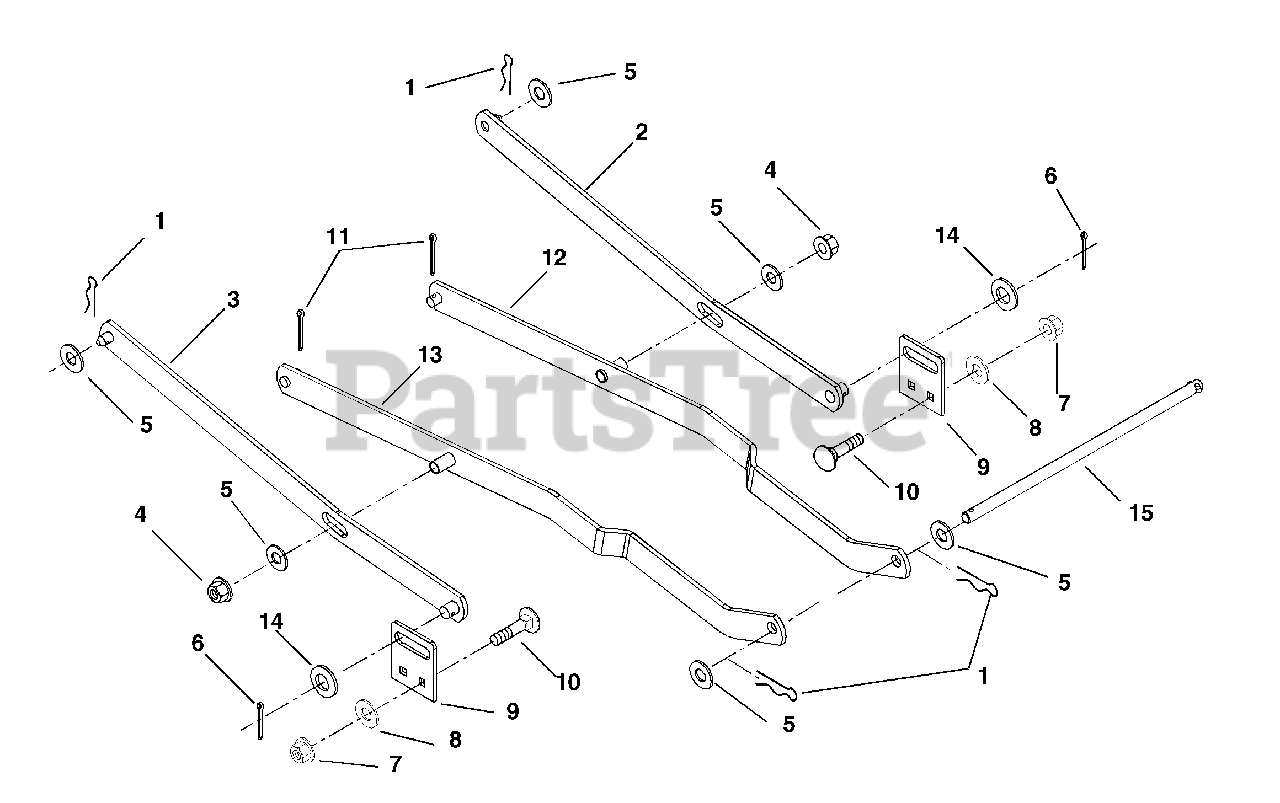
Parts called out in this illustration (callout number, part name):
1	PIN-HAIR-EXT .12X.31X2.37 YWZC
2	ARM, LIFT-LEFT REAR
3	ARM, LIFT-RIGHT REAR
4	@NUT-LK-CTR .62-11 YWZC
5	@WSHR-FL-STL.656X1.31X.095 YWZ
6	@PIN-CTR .16X1.25 EXTPRSQCT YZ
7	NUT-LK-CTR .375-16 YWZC
8	@WSHR-FL-STL.406X.812X.065 YWZ
9	ADJUSTOR, PAN
10	@BLT-RDHDSQNK .38-16X1.00 G2YZ
11	@PIN-CTR .12X1.25 EXTPRSQCT YZ
12	ARM, LIFT-RIGHT FORWARD
13	ARM, LIFT-LEFT FORWARD
14	@WSHR-FL-STL.531X1.06X.095YWZC
15	ROD-DECK HANGER, FRONT
